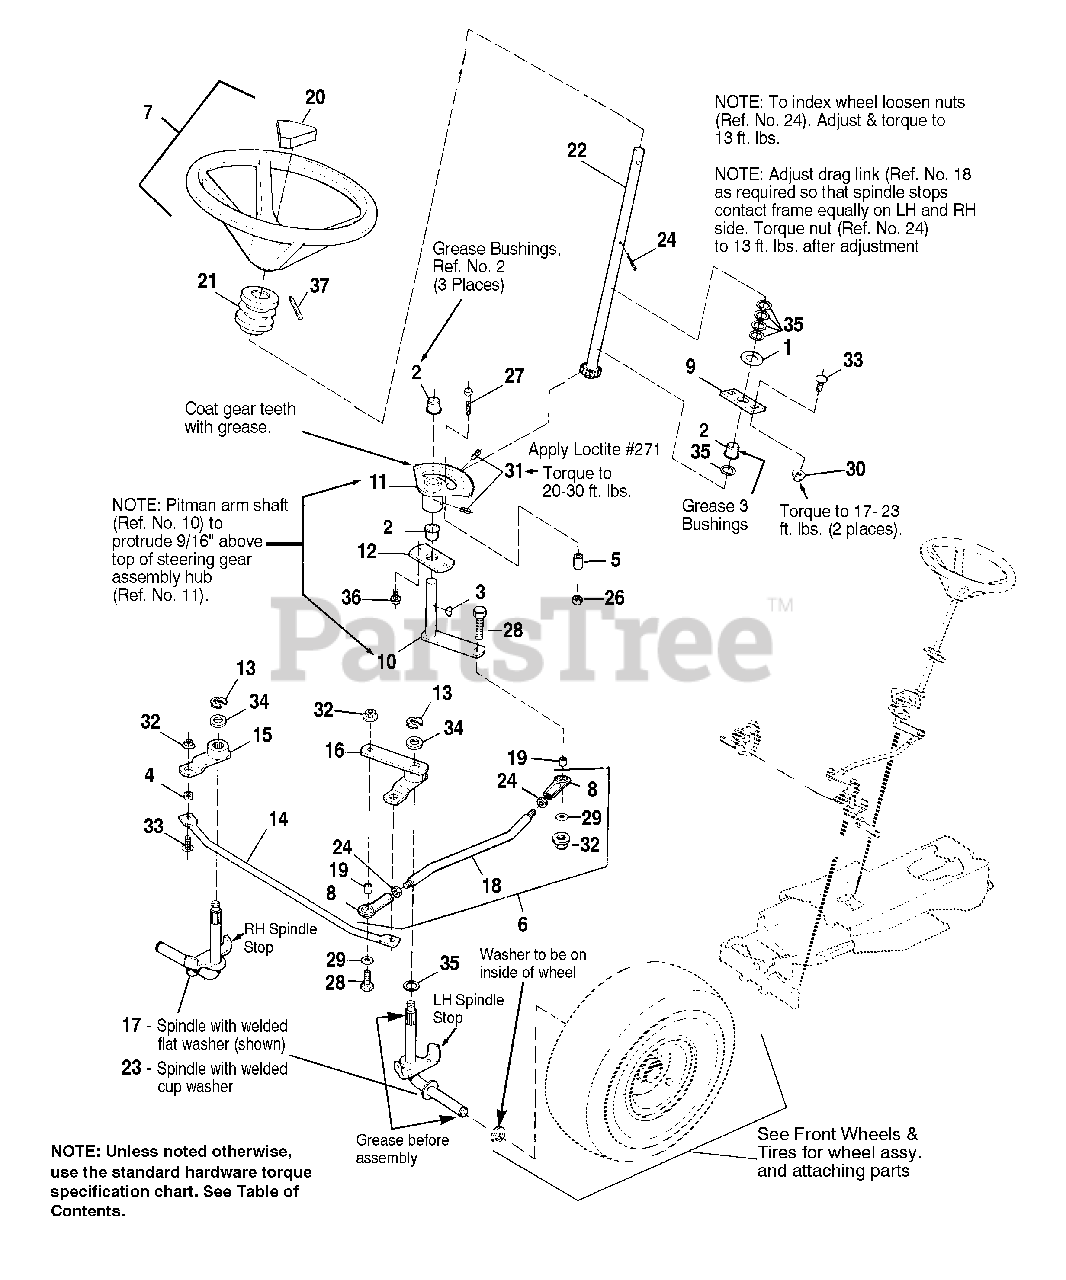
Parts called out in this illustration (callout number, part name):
1	WASHER, Plain
2	BUSHING, Nylon
3	KEY, Hi Pro
5	SPACER, Stop
6	DRAG LINK ASSY.
7	STEERING WHEEL ASSY.
8	BALL JOINT, Flat
9	PLATE, Mounting, Steering
10	PITMAN ARM ASSY.
11	GEAR ASSY., Steering
12	SECTOR MOUNTING PLATE
13	KLIP RING, 5/8
15	STEERING ARM ASSY., RH, Splined
16	STEERING ARM ASSY., LH, Splined
17	SPINDLE ASSY., Splined
20	CAP, Steering Wheel
21	TUBE, Steering
22	SHAFT ASSY., Steering
23	SPINDLE ASSY., Splined
24	JAM NUT, Hex, 1/2-20
26	NUT, Hex, ESNA, Lock, 5/16-18
27	CAPSCREW, Hex, 5/16-18 x 1-1/2
28	CAPSCREW, Hex Hd., 3/8-16 x 1-3/8
29	WASHER
30	NUT, Hex, Flange, Whizlock, 3/8-16
31	SETSCREW, Sq. Hd., 5/16-18 x 1/2
32	NUT, Hex, Flange, 3/8-16
33	CARRIAGE BOLT, 3/8-16 x 1
35	WASHER, Plain, 49/64
36	SCREW, Taptite, 5/16-18 x 1
37	PIN, Spring, 5/8 x 2
